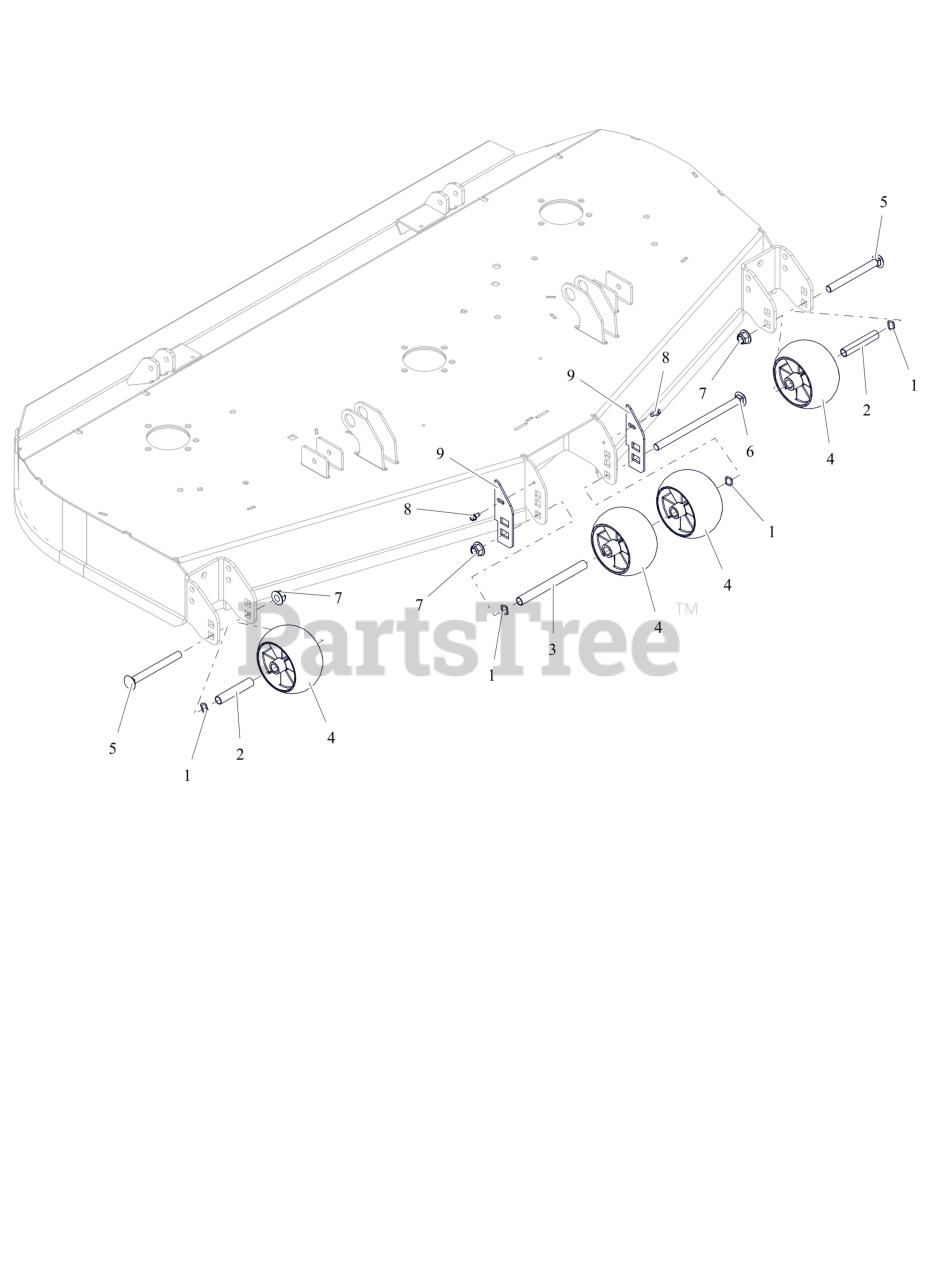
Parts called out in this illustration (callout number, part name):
1	WAVE WASHER .531X.781X.125FH
2	SPACER, .510X.625X3.35
3	SPACER, .510X.625X6.50
4	ANTI-SCALP WHEEL - 5X3 CTR
5	BLT, RHSN .50-13X5.00 G5 ZCC
6	BLT, RHSN .50-13X8.50 G5 ZCC
7	NUT,NYL-FLG .50-13 GF ZCC
8	SCR-TAP .25-20X.50 HWH ZCC
9	PLATE, ANTI SCALP WHEEL 60"
